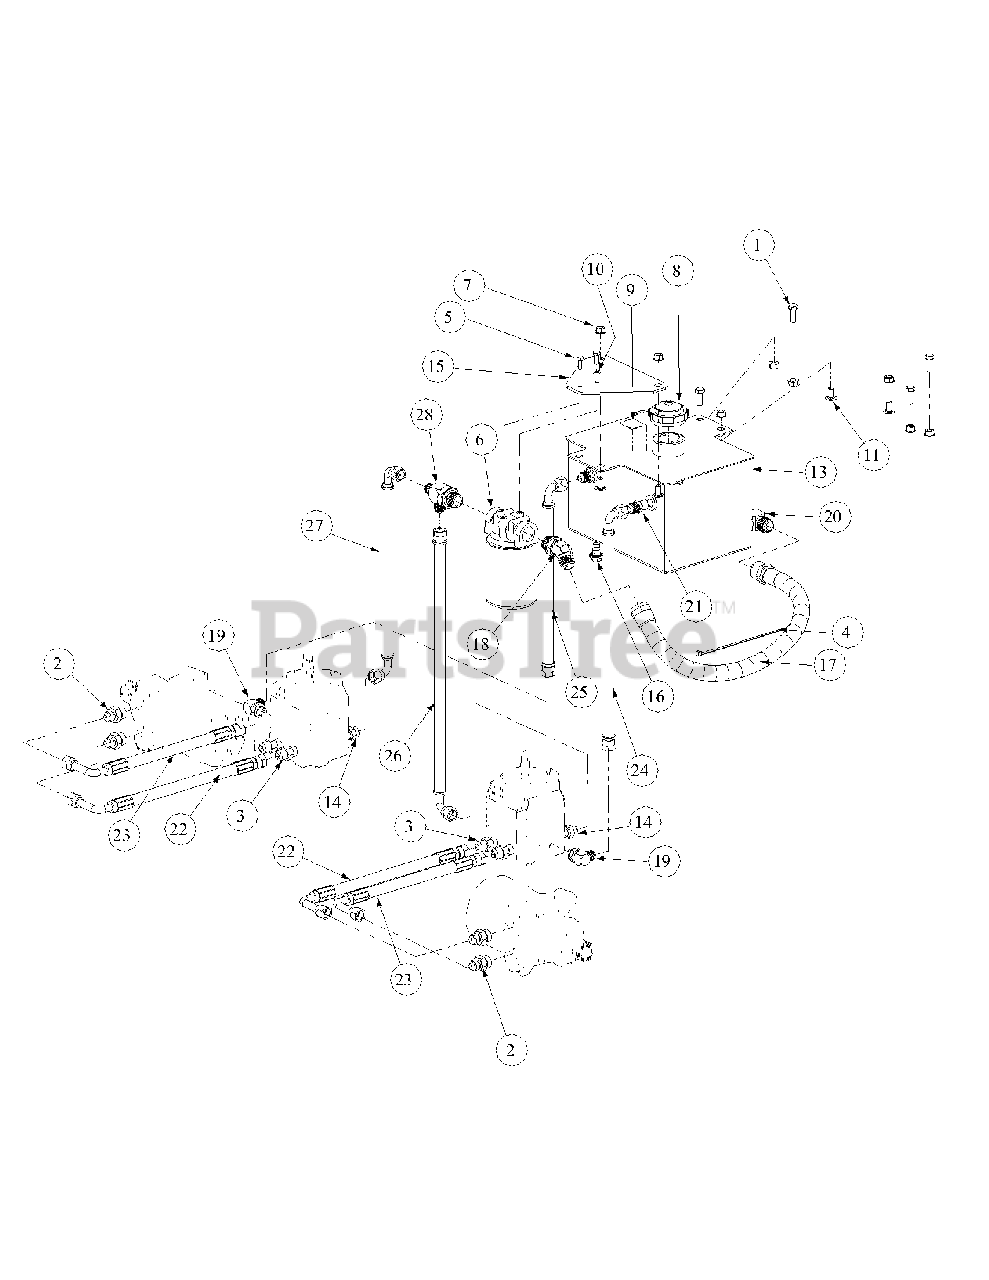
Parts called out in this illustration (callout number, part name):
1	Hex Cap Screw, 3/8-16, 1
2	Fitting 1/2 x 3/4 - O Ring
3	Fitting 1/2 x 3/4 - O Ring to Flare
4	Cable Tie, 3/16 x .05 x 7.4
5	Hex Cap Screw, 1/4-20, .75
6	Filter Head 3/4
7	Hex Nut Flange Lock, 3/8-16
8	Cap, Hydro Oil Tank
9	Decal Oil Only 20W50
10	Lock Washer, 1/4
11	Carriage Bolt, 3/8-16 x .75 LG.
13	Hydraulic Tank Assembly
14	Fitting Connector, 1/2 x 3/8
15	Oil Filter Mounting Plate
16	Oil Pan Drain w/ Seal and Plug
17	Tank to Filter Hose Assembly
18	Connector, 3/4 x3/4
19	Elbow Fitting, 3/8 O-ring, 1/2 Flare
20	Fitting Elbow, 1/2 x 1/2
21	Fitting, 3/8 NPT, 1/2 Flare
22	Long Pressure Hose Assembly
23	Short Pressure Hose Assembly
24	17.75" Return Hose Assembly, RH
25	14" Return Hose Assembly, LH
26	21.25" Supply Hose Assembly, RH
27	15.50" Supply Hose Assembly, LH
28	Tee Fitting, 3/4 x 1/2 x 1/2
